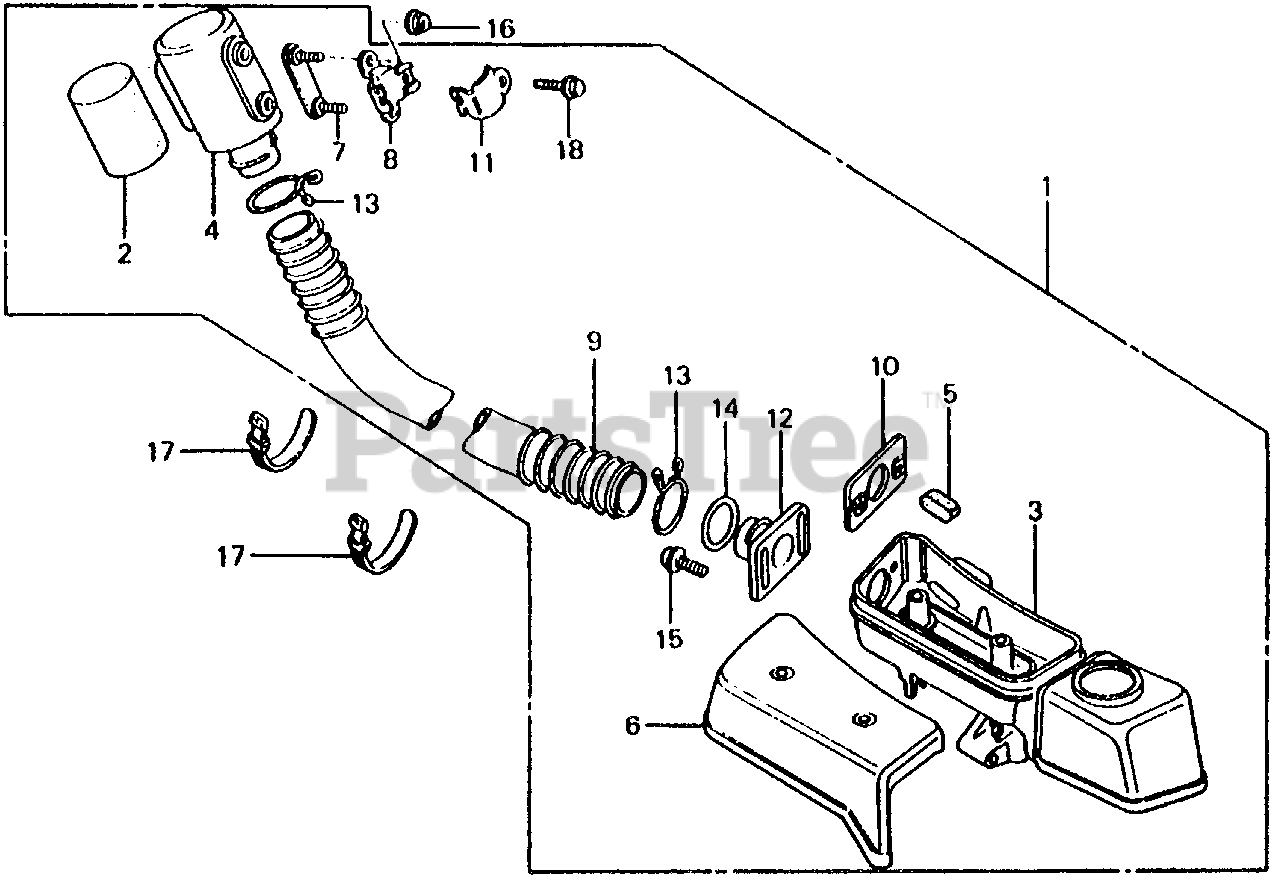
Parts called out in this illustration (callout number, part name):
1	AIR CLEANER KIT, SNORKEL
2	ELEMENT, AIR CLEANER
3	CASE, SNORKEL AIR CLEANER
4	HEAD, SNORKEL AIR CLEANER
5	CAP, SNORKEL AIR CLEANER
6	COVER, SNORKEL AIR CLEANER
7	PLATE, AIR CLEANER SETTING
8	BRACKET A, AIR CLEANER
9	HOSE, SNORKEL AIR CLEANER
10	FLANGE, SNORKEL PIPE
11	BRACKET B, AIR CLEANER
12	PIPE, SNORKEL
13	CLIP, AIR HOSE (27)
14	O-RING (27.7X1.9)
15	SCREW-WASHER (4X16)
16	NUT, FLANGE (6MM)
17	BAND B2, CABLE HARNESS
17	BAND B3, CABLE HARNESS
18	BOLT, FLANGE (6X16)
